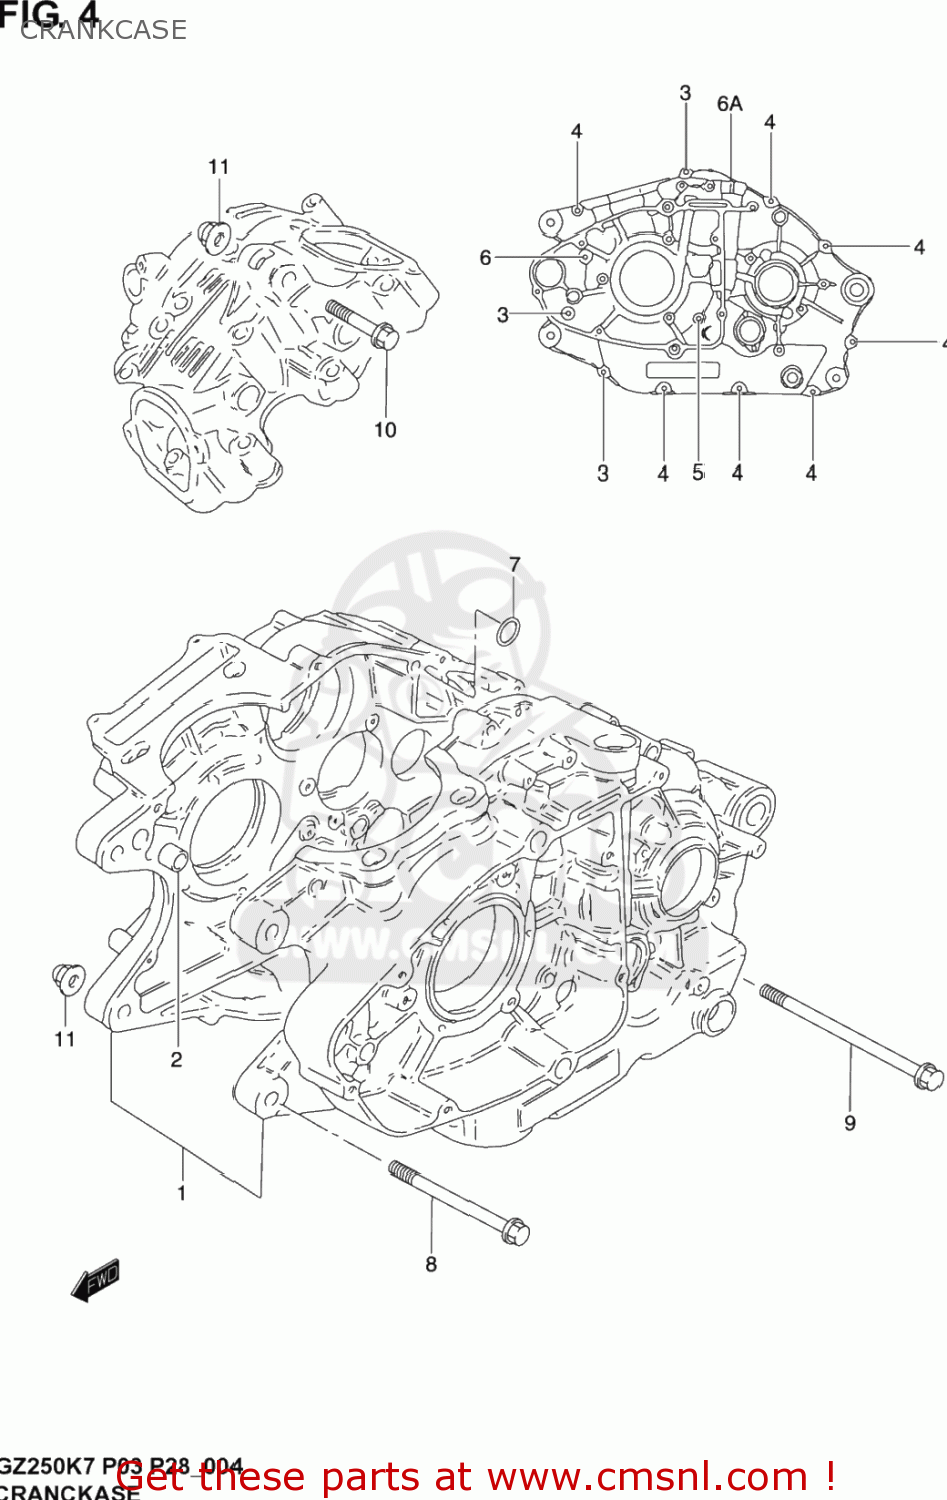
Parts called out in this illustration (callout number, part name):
1	CARTERSET
2	PIN
3	BOLT
4	BOLT
5	BOLT
6	BOLT
6A	BOLT
7	O RING(D:1.9,ID:9.8)
8	BOLT(8X67)
9	BOLT(8X100)
10	BOLT(8X50)
11	NUT
